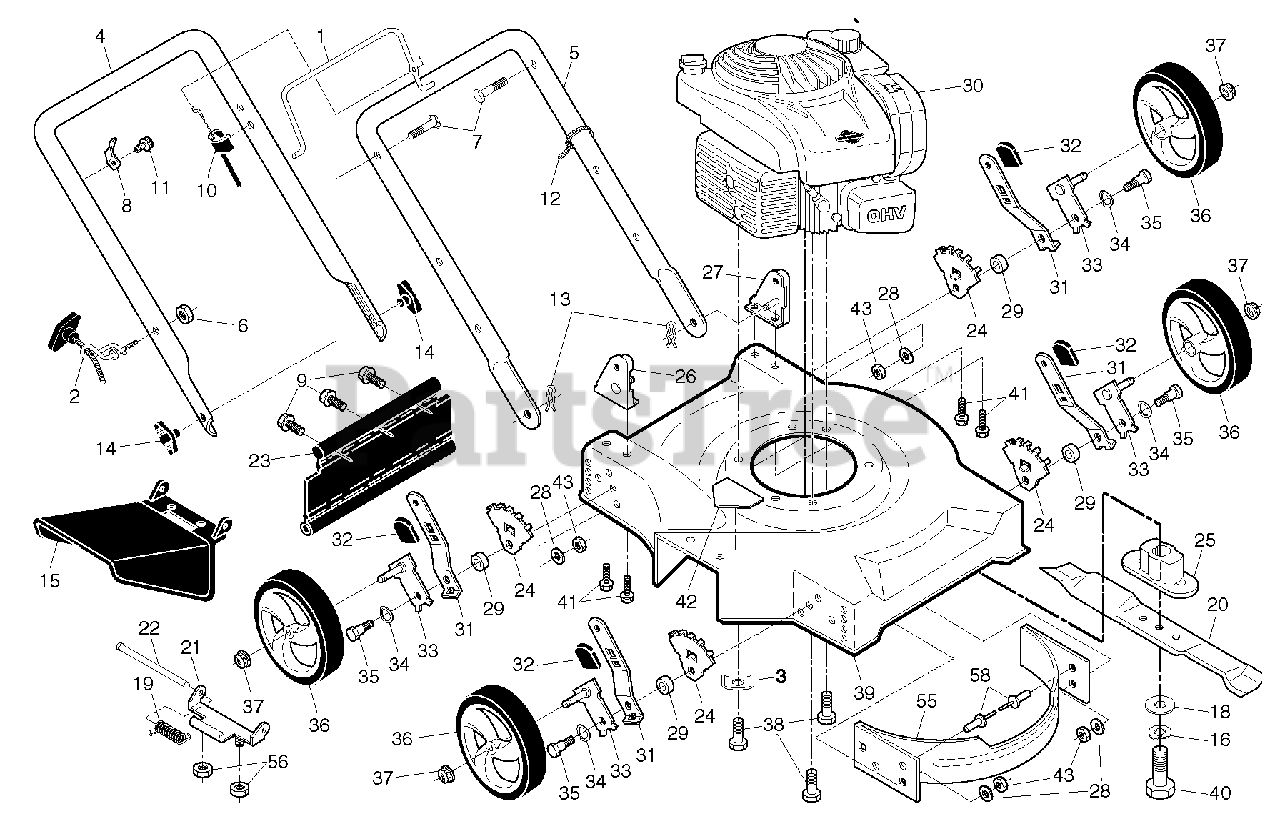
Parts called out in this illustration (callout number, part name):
1	BAIL.CONT.D.STRAIGHT.PUSH.BLK
2	Rope Guide, Blk Zinc Chrom
3	WASHER.ENGINE.BZP
4	HANDLE.UPPER.ECONOMY.BLACK
5	HANDLE.LOWER.D-STRAIT.BLACK
6	T-KNOB.NEW ROPE GUIDE
7	BOLT, HANDLE 5/16-18X1.75
8	BRACKET.UPSTOP.RT
9	SCREW.HEX.WASH.HD.TAPPING
10	CABLE.MZR.RATO.22"LOW.
12	TIE GUIDE
13	HAIRPIN COTTER
15	GUARD.DISCHARGE.ECON.BLK.US/CE
18	WASHER,HARDEN
19	SPRING.SIDE.DISCHARGE
20	Mower Blade, 20" Mulching
21	HINGE DEFLECTOR
22	HINGE ROD
23	SKIRT.ECON.20.SD.WHL.ADJ
24	WHEEL ADJ BRACKET FRONT
25	ADAPTOR.BLADE.7/8
26	HANDLE BRACKET ASM. RH
27	HANDLE BRACKET ASM. LH
28	WASHER
29	SPACER.HEIGHT.ADJUSTER
31	SELECTOR SPRING, FRONT
33	AXLE ARM ASSY.
34	WASHER.CURVED.CYLINDRICAL
35	SHOULDER BOLT 5/16-18
36	WHEEL.7X1.5.DMD.3SPK.BLACK.
37	NUT.HEX.FLANGE.3/8-16.LOCKNUT
38	BOLT 3/8-16X1-1/8
39	KIT.HSG.20SD.PUSH.MS665.TRI
40	SCREW, HEX HD 3/8-24 X 1-3/8
41	SCREW.5/16-18X3/4
42	No Step Decal
43	NUT.71038.31-18.HEX.NYLOCK
55	BAFFLE
56	LOCKNUT.NYLOC.1/4-20
58	RIVET BLIND
